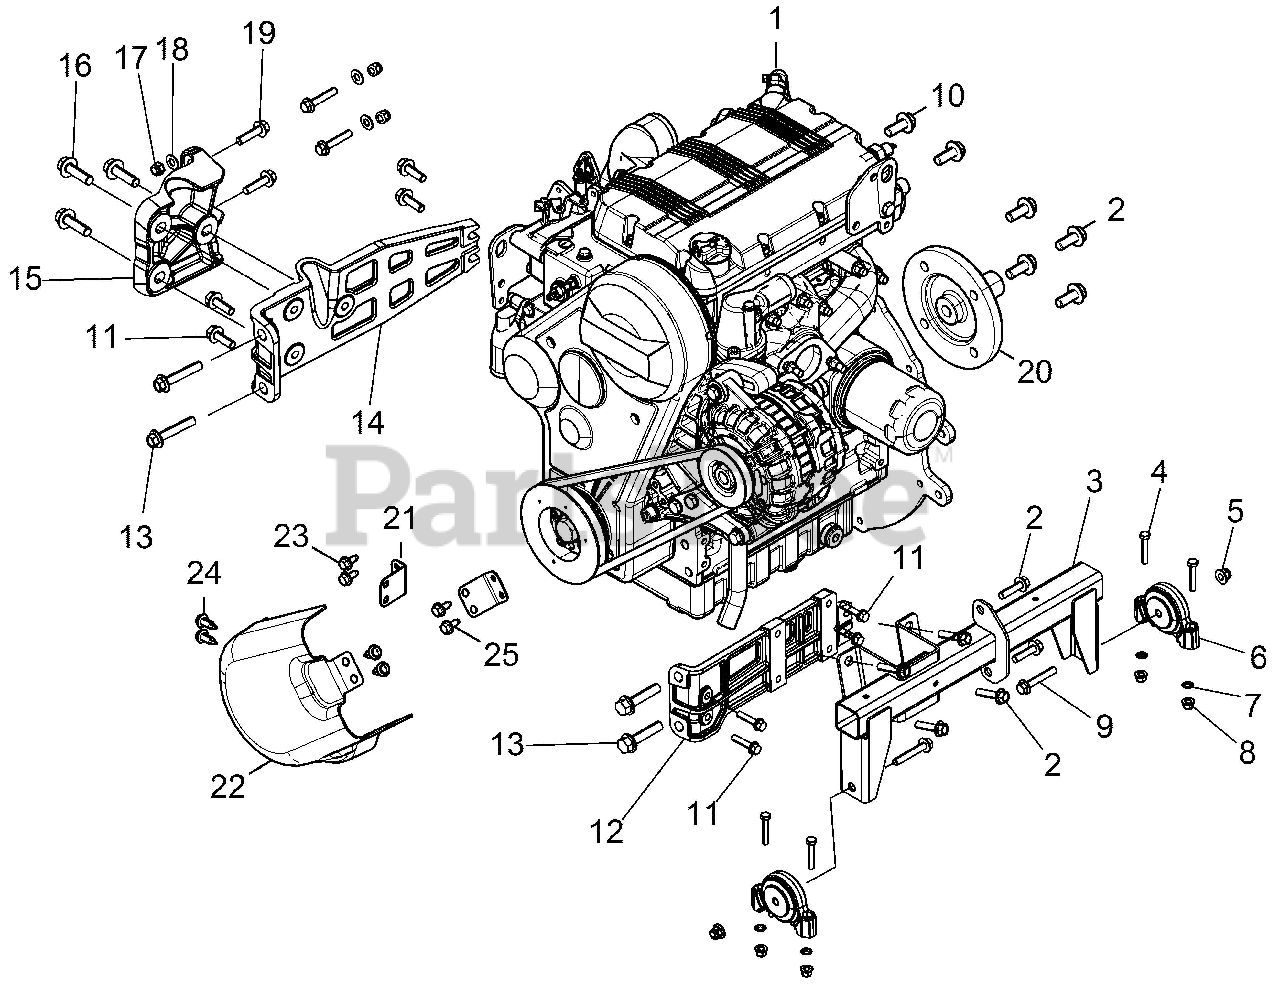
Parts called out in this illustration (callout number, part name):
1	ASM-ENG KDW1003-5143
2	SCR-M10X1.5X25 8.8 HXFL ZOD
3	WELD-MOUNT,ENGINE,BLK
4	SCR-HH M8X1.25X45 8.8 ZOD
5	NUT-M10X1.25,FLG,NYLOC-OLIVE D
6	MOUNT-ISOLATOR,DRIVELINE
8	NUT-M8X1.25,FLG,NYLOC-OLIVE D
9	BOLT-M10X1.25X60,HXFLG-OLIVE D
10	SCR-HXFL-M8X1.25X20 8.8 ZOD P3
11	BOLT-M8X1.25X25,HXFLG-OLIVE D
12	COUPLER-L-ENGINE,FRONT
13	SCR-HXFL-M12X1.75X30 ZOD
14	COUPLER, ENGINE, GEARCASE
15	COUPLER-L-ENGINE,GEARCASE
16	SCR-HXFL-M10X1.5X35 10.9 ZOD D
17	NUT-M10X1.5 HFN NYLOC ZOD
18	WASHER,3/8 FW
19	SCR-HXFL-M10X1.5X50 10.9 ZOD
20	ADAPTER-CLUTCH,DSL
21	BRKT,BELT GUARD,MOUNT,BLK
22	COVER,DEBRIS
23	BOLT,M6X1.0X15,HXFLG,TAP/T-OD
24	RIVET-TUFLOK,.315-.325X.787 (5
